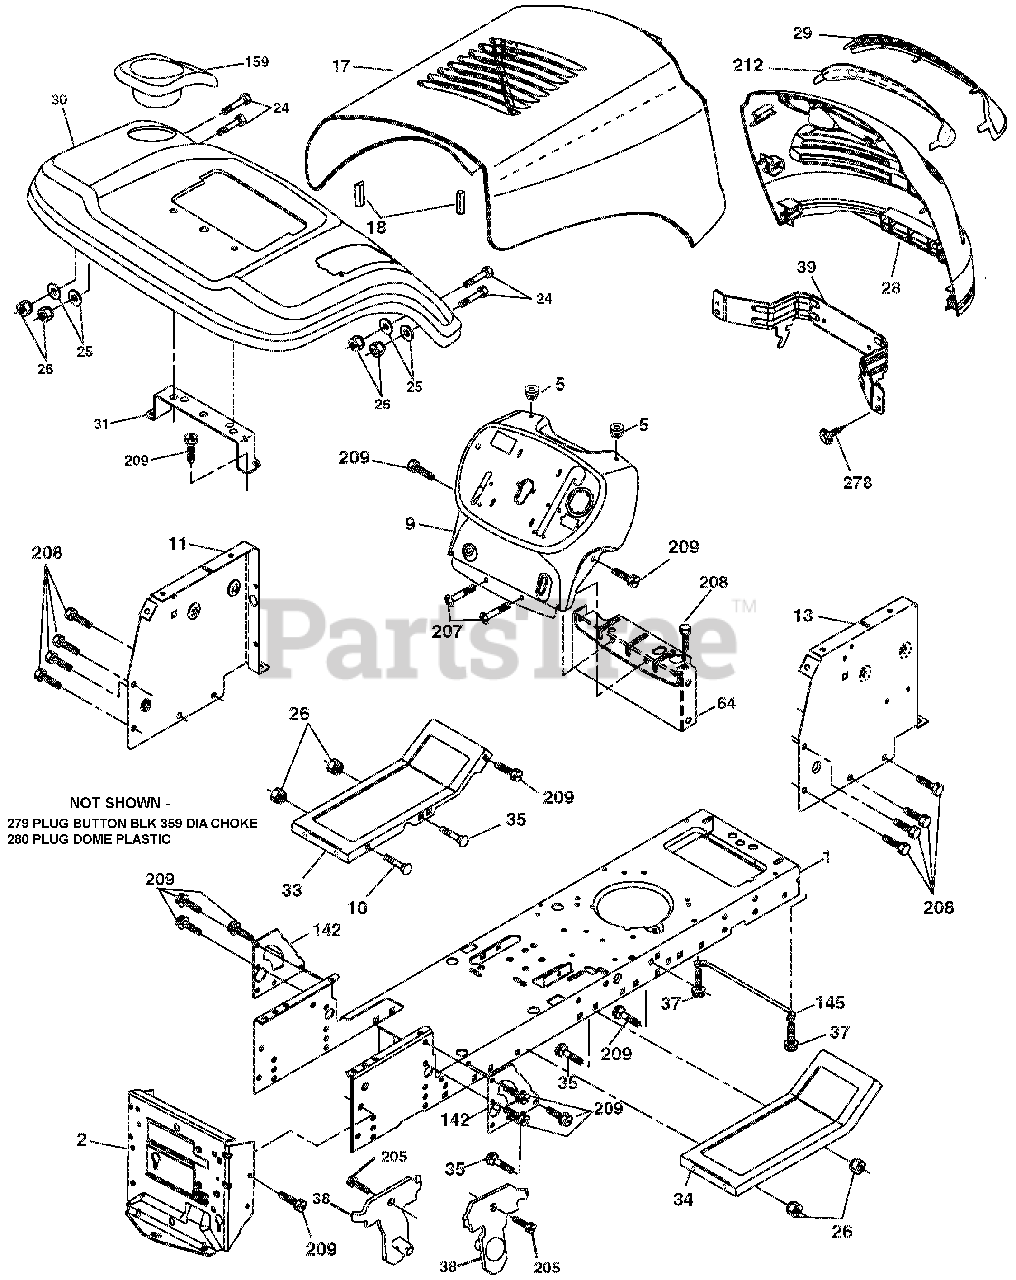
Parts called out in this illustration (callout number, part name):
1	Chassis
2	Drawbar, Stretch
5	Bumper, Hood/Dash
10	Panel Slkscr Dash RH
11	Panel Dash LH
13	Panel Slkscr Dash RH
18	BUMPER.HOOD.LARGE. 1.75"
24	Bolt Fin Hex 3/8-16 unc x 1 Gr
25	Washer 13/32 x 13/16 x 12 Ga.
26	Locknut, Washer Insert 3/8-16
28	Grille
29	Lens Grille Bar
30	FENDER
31	Bracket Fender Repl 109873X
33	Footrest Pnt LH
34	Footrest Pnt RH
35	Bolt Rdhd Sht Sqnk 3/8-16 x 3/
37	SCREW.THDROL.5/16-18 X 1/2TYTT
38	Bracket Asm. Pivot Mower
39	Bracket Pivot
64	Dash Lower
142	Plate Reinforcement
145	ROD.PIVOT.HOOD
159	Cupholder
205	Screw Thdrol 3/8-16 x 1/2
207	Screw 5/16-18 x 1/2
208	SCREW.THDROL.3/8-16X1/2.TYT.BL
209	SCREW.HEXWSH THDR3/8-16X3/4.BL
212	Insert Lens Reflect
279	Plug Button Blk 359 Dia Choke
280	Plug Dome Plastic
